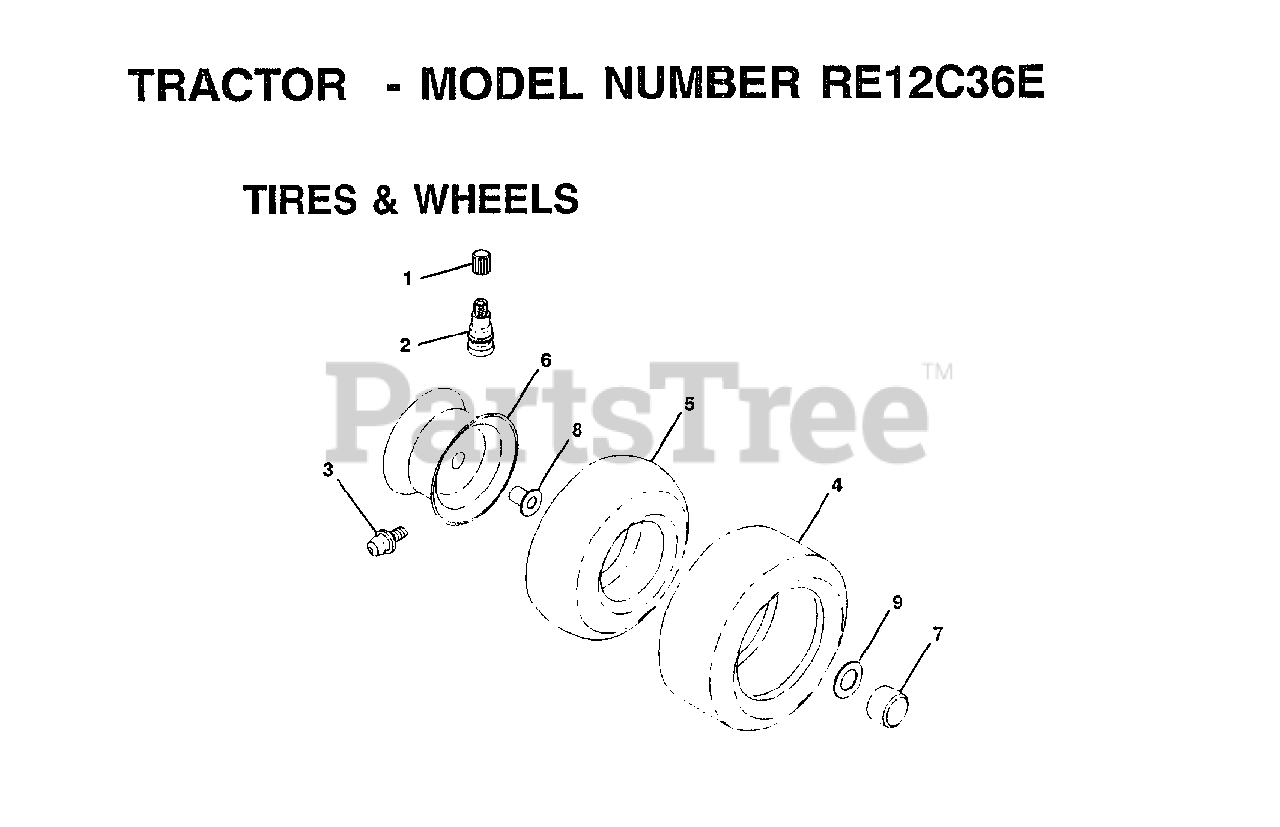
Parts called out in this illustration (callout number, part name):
1	VALVE CAP
2	VALVE STEM LT
3	FITTING LT
5	TUBE.5.3/4.5/6
5	TUBE.16X6.5/7.5-8
6	"RIM FRONT 6"""
6	"RIM ASM REAR 8"""
7	HUB CAP
8	"FLANGE, BEARING"
9	WASHER
